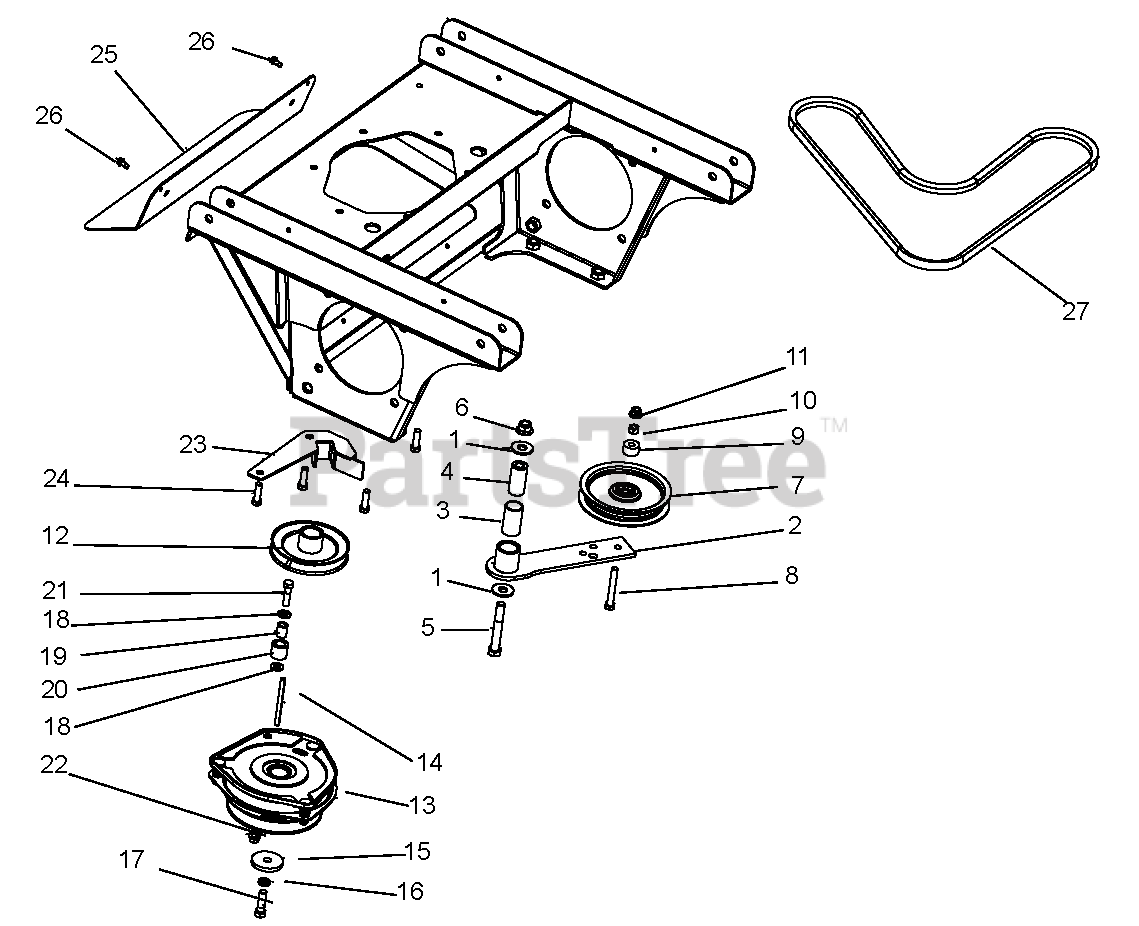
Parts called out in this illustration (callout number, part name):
1	Washer, Flat Steel.563 x 1.38 x .109YWZC
2	Weldment, Idler Arm Ground Drive
3	Bushing, 1.00 x 1.125 x 1.937
4	Bushing, Spacer .502 x .997 x 2.03 PM
5	Bolt, Hex .50-13 x 3.50 GR5 YWZC
6	Nut, Locking Nyloc Flange .50-13 YWZC
7	Idler, Flat 5.00 x .38
8	Bolt, Hex .38-16 x 2.75 GR5 YWZC
9	Spacer .390 x 1.000 x .562
10	Nut, Locking Center .38-16 YWZC
11	Nut, Locking Nyloc Flange .38-16 YWZC
12	Sheave, Engine 5.426 x 1.127
13	Clutch, Electric-OGURA GT3.5-VP01R
14	Key, Square .25 x 3.50 x .25 SAE
15	Washer, Flat Steel .469 x 2.00 x .25 YWZC
16	Washer, Lock .44 x .109 REG YWZC
17	Bolt, Hex .44-20 x 1.50 G5 YZ EP80
18	Washer, Flat Steel. 406 x .812 x .065 YWZ
19	Bushing, S.407 x .625 x .813 ST
20	Bumper, Rubber .62 x 1.0 x .88 LG
21	Bolt, Hex .38-16 x 1.50 GR5 YWZC
22	Nut, Locking Top Flange .38-16 YWZC
23	Weldment, Clutch Stop
24	Bolt, Hex .38-16 x 1.25 FTHG5 EP30YZ
25	Shield, Muffler Heat
26	Screw, Tap .25-20 x .50 Hex Washer Head TR YWZ
27	V-Belt, Cogged B-Raw Edge
